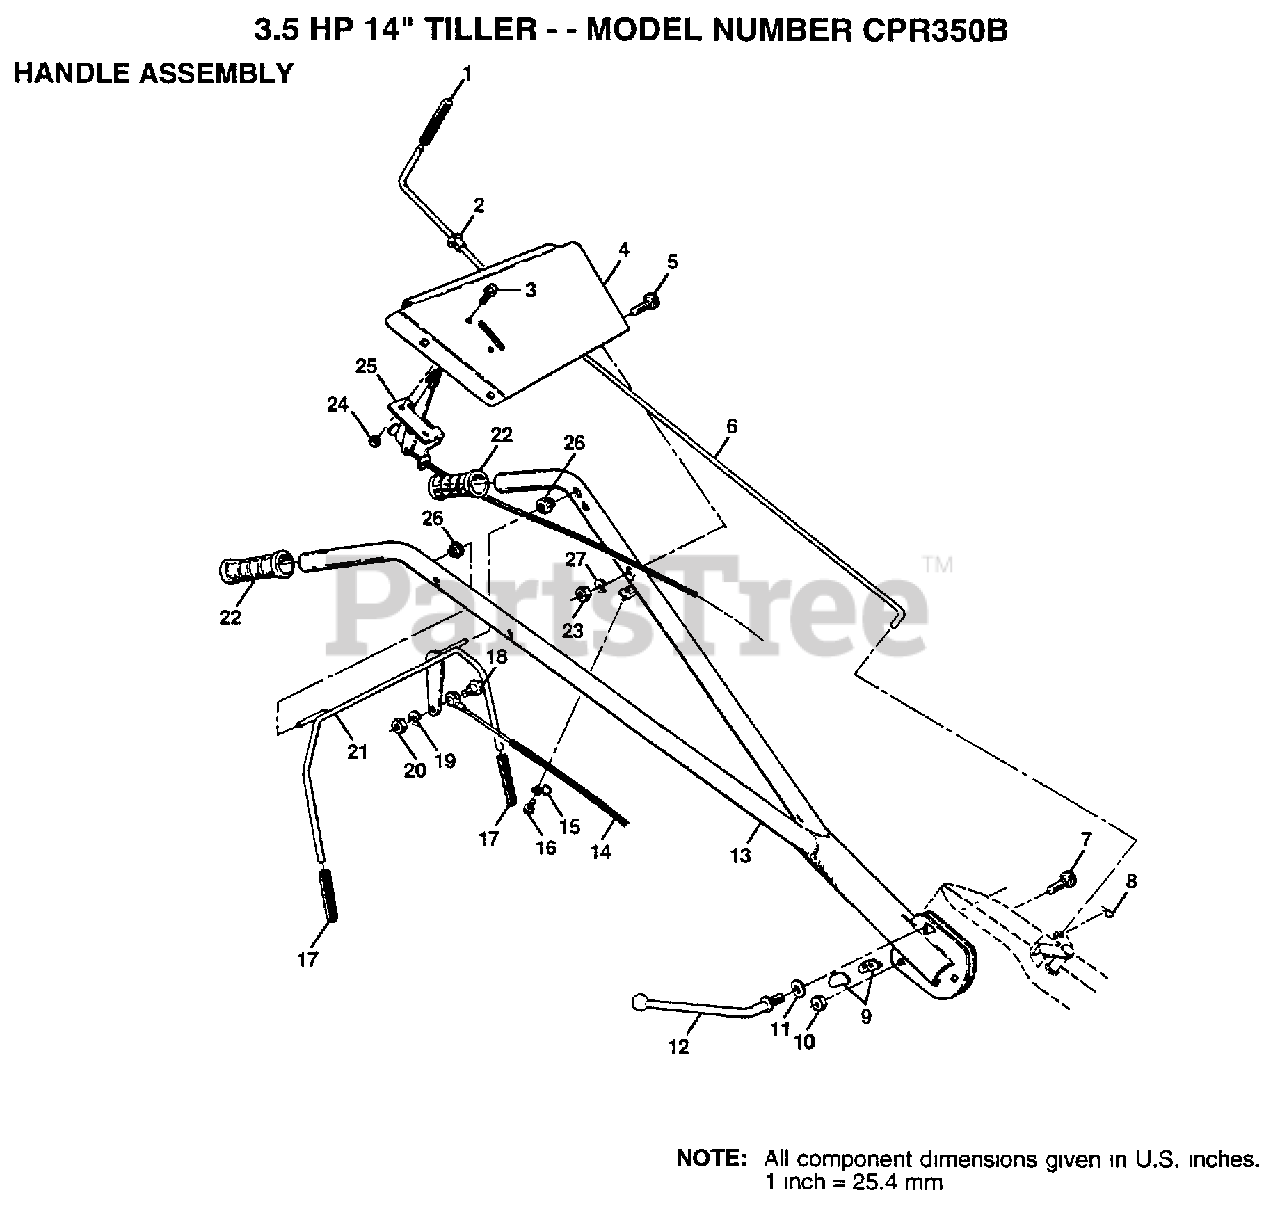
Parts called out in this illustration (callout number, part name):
1	GRIP TI
2	BUSHING
3	SCREW.PNHD.10-24
5	BOLT CARRIAGE CRT
6	ROD SHIFT CRT
7	BOLT D
8	RETAINER M
9	LOCK CRT
10	LOCKNUT
11	WASHER CRT
12	LEVER LOCK CRT
14	CABLE.CLUTCH.CRT
15	CONDIUT CLIP T
17	GRIP BAR CRT
18	SHOULDER BOLT ST
19	LOCKWASHER
21	HANDLE BAR CRT
22	GRIP HDLE NUBBED
23	NUT
25	"CONT,THROTTLE"
27	LOCKWASHER
